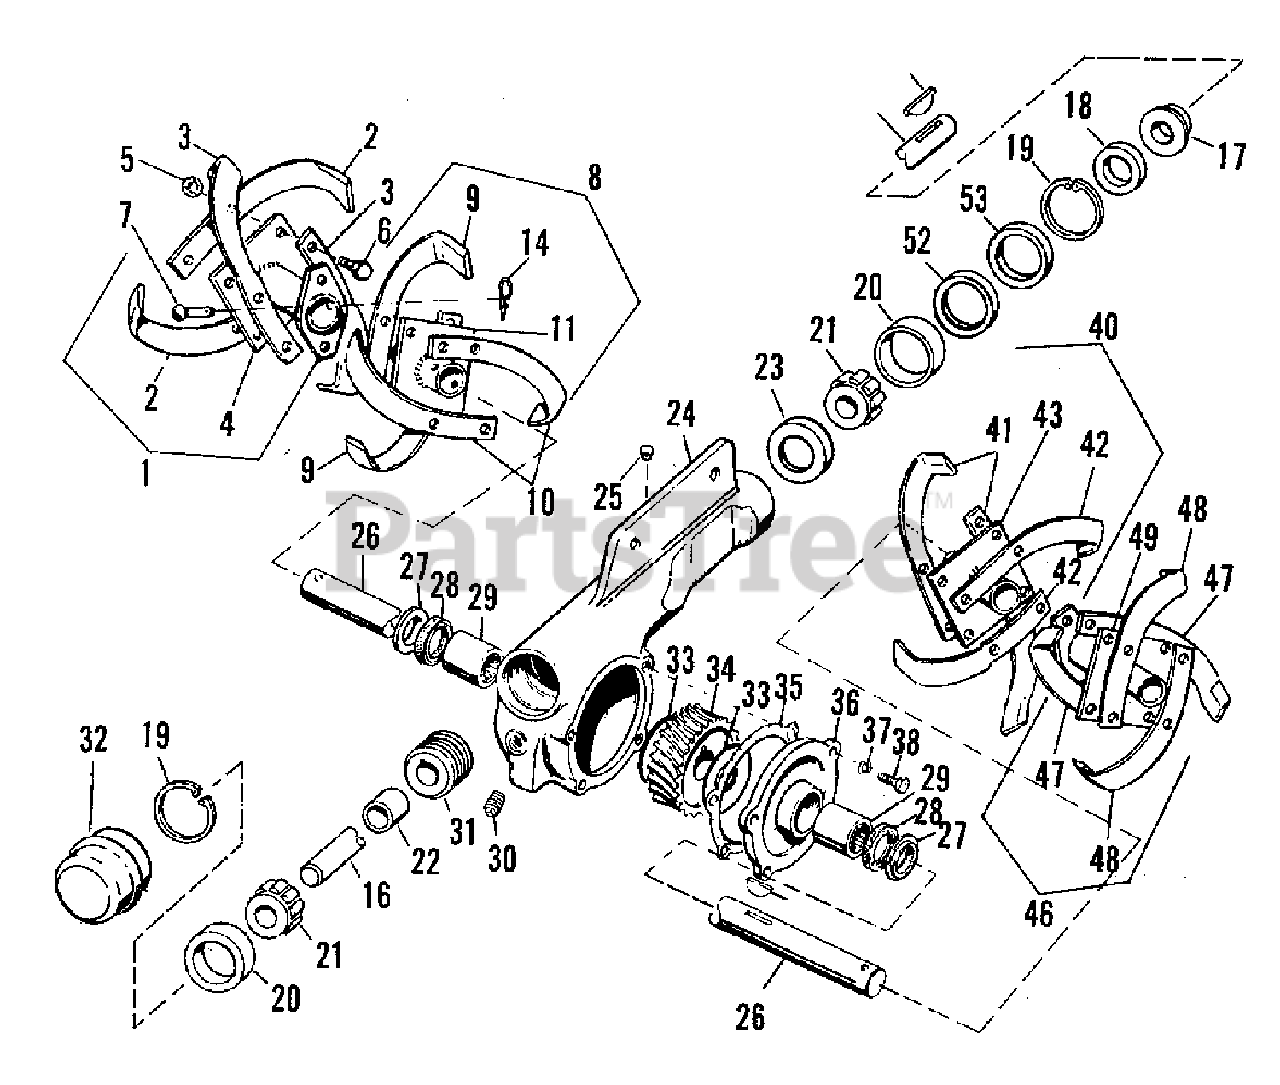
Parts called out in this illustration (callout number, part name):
1	BLADE ASSEMBLY, Tine, Outer (R.H.)
2	BLADE, Tine (R.H.)
3	BLADE, Tine (L.H.)
4	PLATE, Outer
5	NUT, Hex, Lock, 7/16-20
6	SCREW, Hex Cap, 7/16-20 x 1-1/4
8	BLADE ASSEMBLY, Tine, Inner (R.H.)
9	BLADE, Tine (R.H.)
10	BLADE, Tine (L.H.)
11	PLATE, Inner
12	NUT, Hex, Lock, 7/16-20
13	SCREW, Hex Cap, 7/16-20 x 1-1/4
14	PIN, Cotter, 1/8 x 3/4
15	KEY, 3/16 x 7/8
20	CUP, Bearing
21	BEARING, Roller
24	HOUSING, Worm Drive
26	SHAFT, Worm Gear
29	BEARING, Needle
30	PLUG, Pipe, 3/8"
31	WORM, Right Hand
33	WASHER, Thrust
34	GEAR, Worm (R.H.)
37	WASHER, Lock, 1/4
38	SCREW, Hex, Cap, 1/4-20 x 5/8
39	KEY, Woodruff #91
40	BLADE ASSEMBLY, Tine, Inner (L.H.)
41	BLADE, Tine, (R.H.)
42	BLADE, Tine (L.H.)
43	PLATE, Inner
44	NUT, Hex, Lock, 7/16-20
45	SCREW, Hex Cap, 7/16-20 x 1-1/4
46	BLADE ASSEMBLY, Tine Outer (L.H.)
47	BLADE, Tine (R.H.)
48	BLADE, Tine, (L.H.)
51	SCREW, Hex Cap, 7/16-20 x 1-1/4
52	RING, Backing
53	RING, Backing
